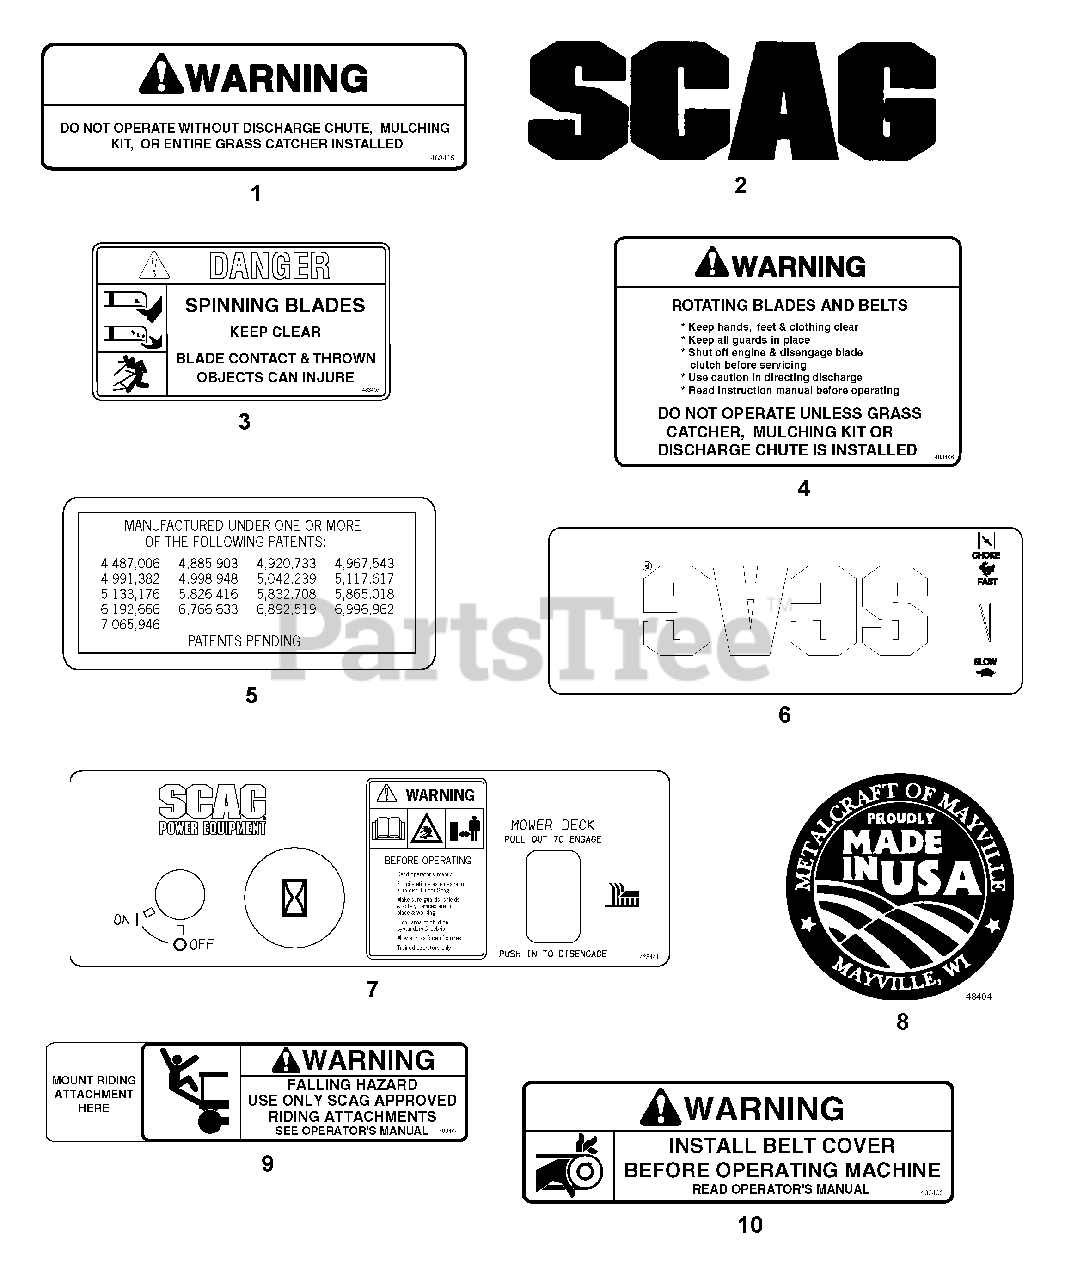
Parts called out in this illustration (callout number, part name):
1	Decal, Discharge Chute
2	Decal, Scag Logo
3	Decal, Danger-Spinning Blades
4	Decal, Warning-Rotating Blades
5	Decal, Patents
6	Decal, Instrument Panel - Front
7	Decal, Instrument Panel - Rear
8	Decal, Metalcraft - Made in USA
9	Decal, Sulky Attachment
10	Decal, Belt Cover
